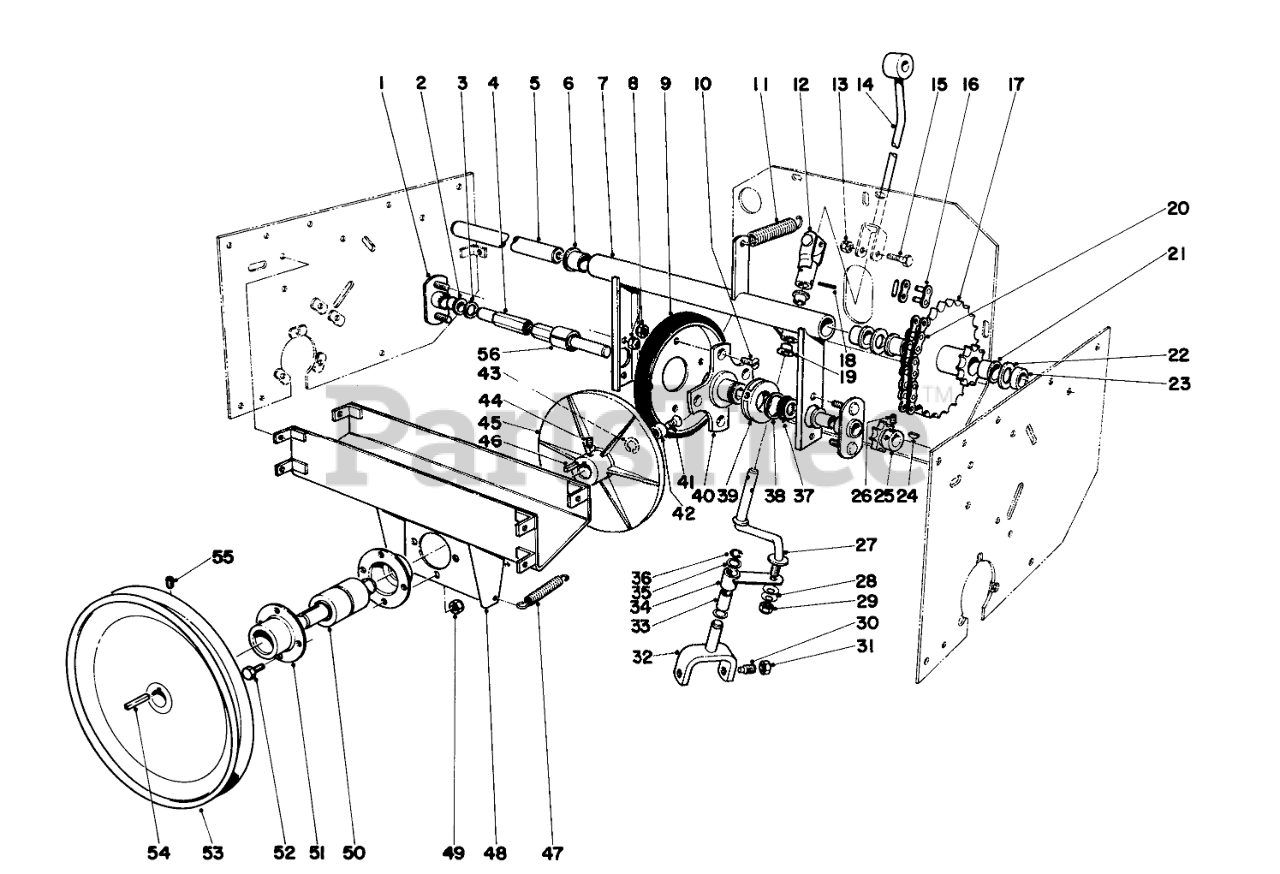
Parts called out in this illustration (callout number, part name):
1	Adj. Plate (Incl. Ref. #2)
2	Bushing
3	WASHER-FLAT
4	Shaft Friction Wheel
5	Pivot Shaft
6	3/4IDX1LG FLANGE BSHG
7	Clutch Control (Incl. Ref. #6 & 19)
8	NUT-LOCK, NI
9	Disc Assembly
11	Spring (Friction Wheel)
12	U Joint
13	NUT-LOCK, NI
14	Trunion
15	SCREW-HH
16	LINK-CONNECTING
17	Sprocket Hub (Incl. Ref. #21)
18	PIN-SPRING
19	BUSHING-FLANGE
20	Chain (Incl. Ref. #16)
21	Bushing
22	THRUST WASHER
23	Spacer Pivot Shaft
24	KEY-WOODRUFF
25	SPROCKET
26	SCREW-SET, HSH
27	Connecting Rod
28	WASHER-SPRING
29	NUT-LOCK
30	Set Screw
31	NUT-JAM
33	Bushing
34	Shift Rod (Incl. Ref. #33)
35	Thrust Washer
36	E-RING
37	RING-RETAINING
38	WASHER-THRUST
39	Ring Slider
40	Hub Traction
41	5/16-18X7/8 FLT HD MS
42	Spacer-Friction Wheel
43	Snap Ring
44	SCREW-SET, HSH
45	Plate Friction
46	Key Square
47	Spring
48	Bulkhead
49	NUT-LOCK, NI
50	Shaft-Friction Plate
51	Bearing Housing
52	SCREW-HH
53	Pulley
54	KEY-SQUARE
55	SCREW-HSH
56	Spacer
